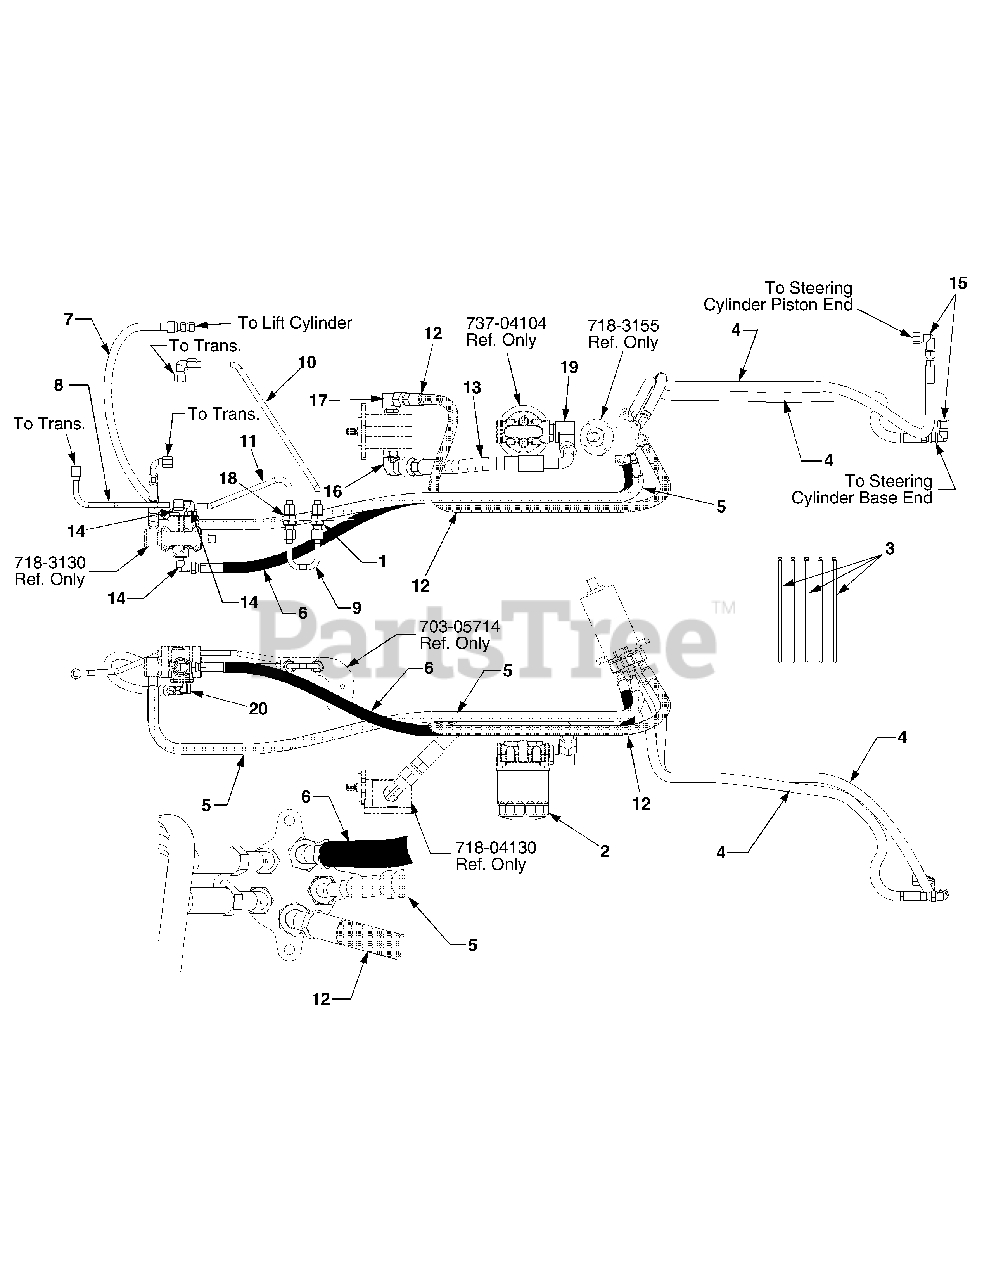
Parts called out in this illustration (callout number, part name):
1	Nut, Hex Jam, 9/16-18 GR5
2	Filter, Oil
3	Tie, Cable
4	Hose, Steering
5	Hose, Steering - Tank
6	Hose, Lift Inlet
7	Hose, Lift Cylinder
8	Tube, Cylinder Return
9	Tube, U Return
10	Tube, Return Tank
11	Tube, Return
12	Hose, Steering Pressure
13	Hose, Aux. Pump-Filter
14	Fitting, 90 Degree
15	Fitting, 90 Degree Swivel
16	Fitting, Elbow
17	Fitting, 90 Degree
18	Fitting, Bulkhead
19	Fitting, 90 Degree
20	Fitting, 90 Degree
